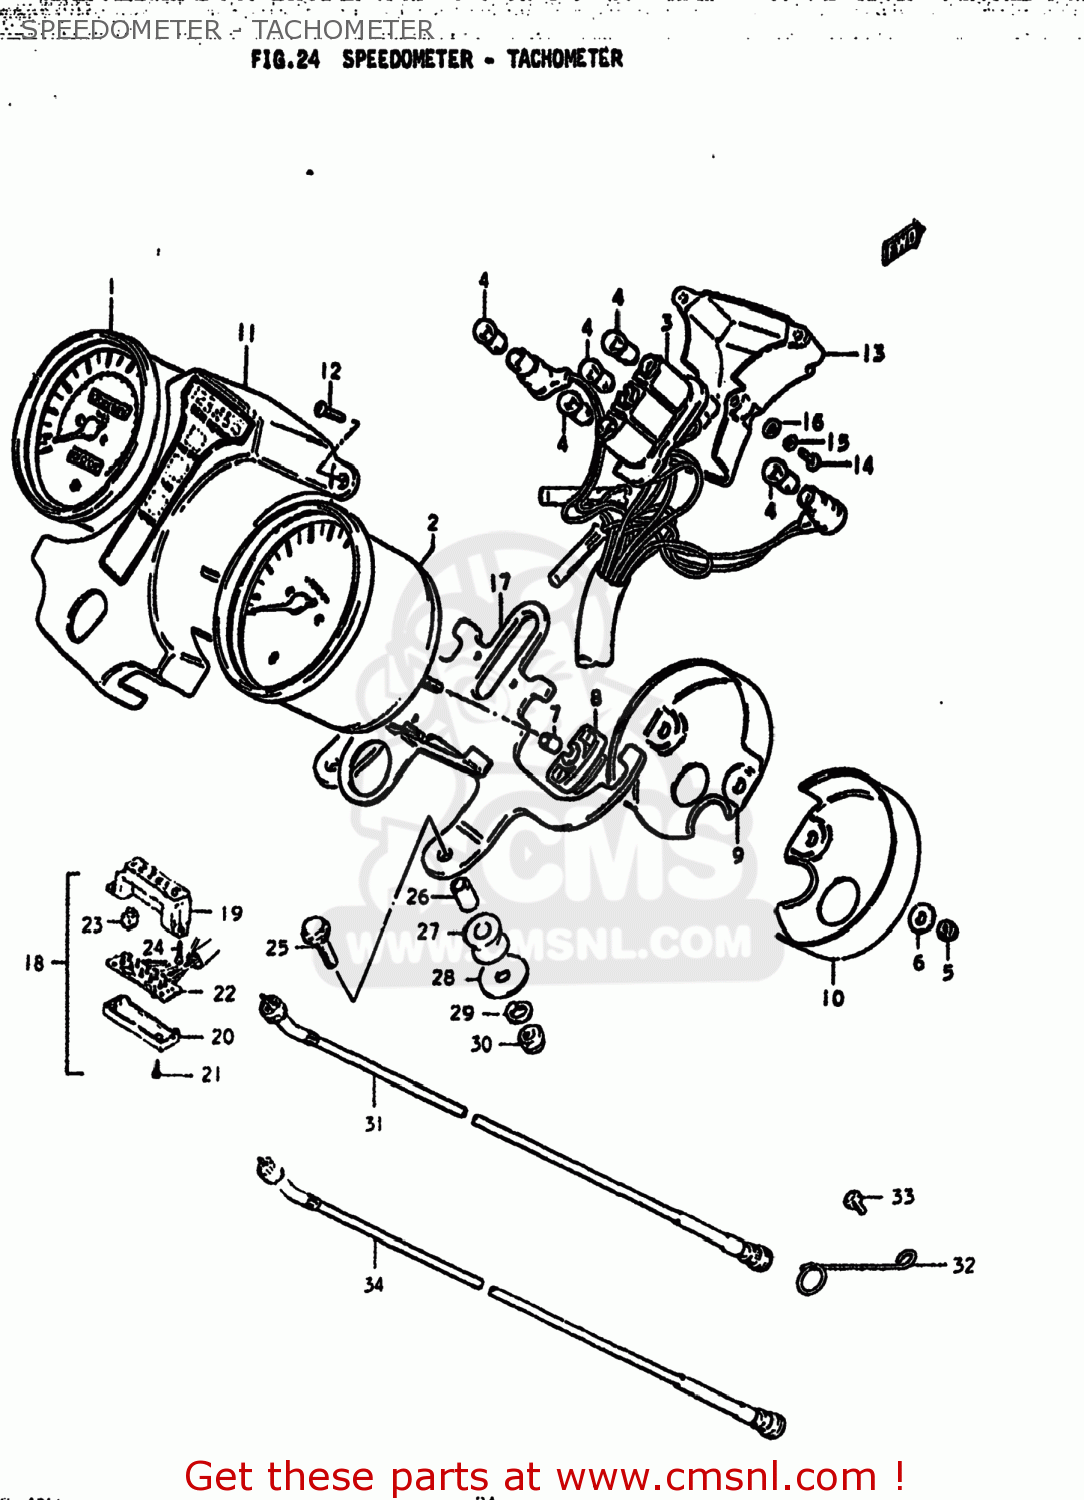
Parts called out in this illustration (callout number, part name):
1	SPEEDOMETER ASSEMBLY
2	TACHOMETER
3	SOCKET,METER
4	BULB(12V3.4W,STANLEY,A72A)
5	NUT
6	WASHER (5.5X16X1.2)
7	SPACER
8	CUSHION,METER
9	UNDER COVER,TACHOMETER
10	UNDER COVER,TACHOMETER
11	CASE,PILOT BULB
12	SCREW
13	COVER,PILOT BULB CASE
14	SCREW(4X16)
15	WASHER,PILOT UNDER CASE
16	WASHER
17	BRACKET,METER
18	INDICATOR ASSEMBLY,GEAR POSITION
19	CASE,GEAR INDICATOR
20	COVER,LWR
21	SCREW,GEAR INDICATOR
22	SOCKET,GEAR INDICATOR
23	BULB(14V1.12W)
24	SCREW
25	BOLT
26	SPACER (6.1X8X15.5)
27	CUSHION
28	WASHER
29	LOCK WASHER
30	NUT
31	CABLE ASSEMBLY,SPEEDOMETER
32	GUIDE,SPEEDOMETER CABLE
33	BOLT, UPPER
34	CABLE ASSEMBLY,TACHOMETER
